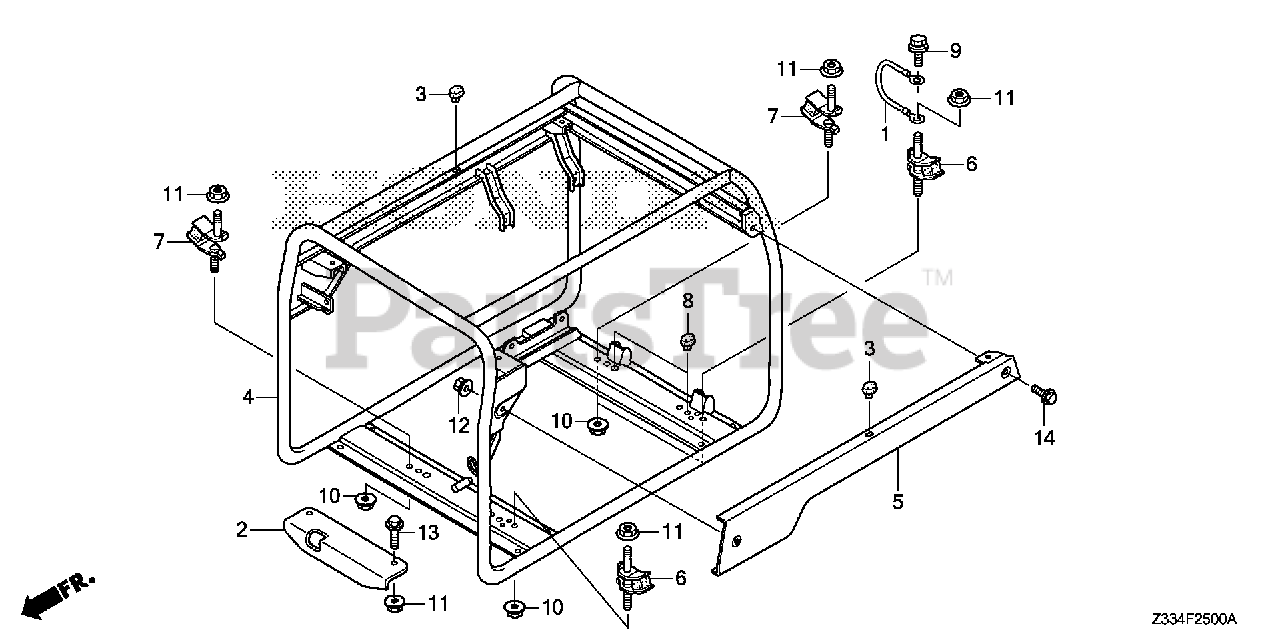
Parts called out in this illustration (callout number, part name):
1	CABLE, SUB-GROUND
2	BRACKET, STOPPER
3	RUBBER, FUEL TANK MOUNTING
4	FRAME *NH105* (CL) (MAT BLACK)
5	FRAME, R. SIDE *NH105* (MAT BLACK)
6	RUBBER (LOWER)
7	RUBBER (LOWER)
8	RUBBER, BUMP STOP
9	BOLT, GROUND (6X16) (WASHER 12.5MM) (ZN)
10	NUT, FLANGE (8MM)
11	NUT, FLANGE (10MM)
12	NUT, FLANGE (6MM)
13	BOLT, FLANGE (10X40)
14	BOLT, FLANGE (6X12)
